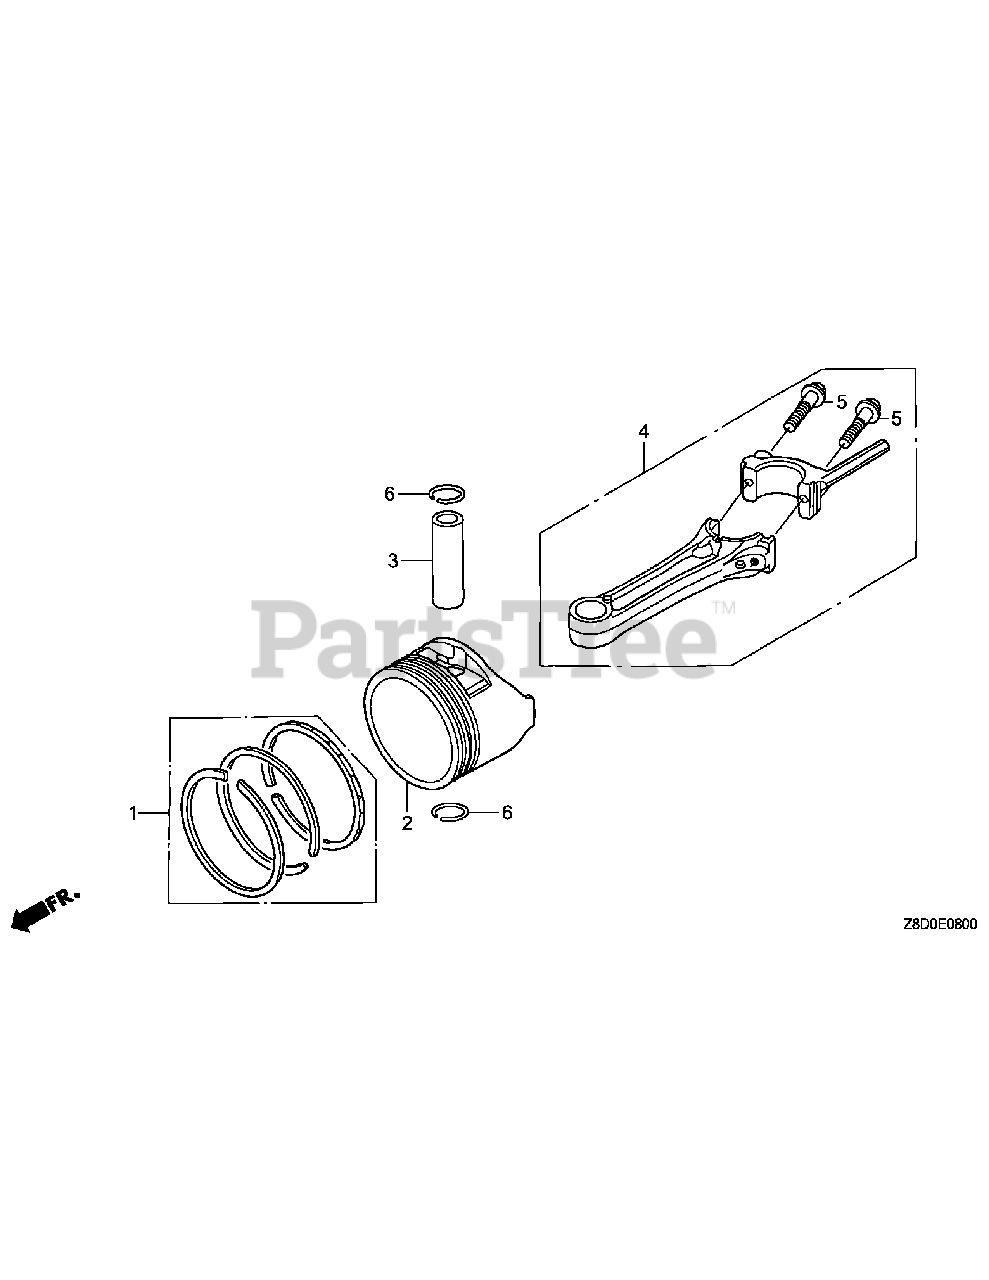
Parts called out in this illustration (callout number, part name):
1	Piston Ring Set (Teikoku)
2	Piston
3	Piston Pin
4	Connecting Rod Assembly
5	Connecting Rod Bolt
6	Piston Pin Clip, 13mm
